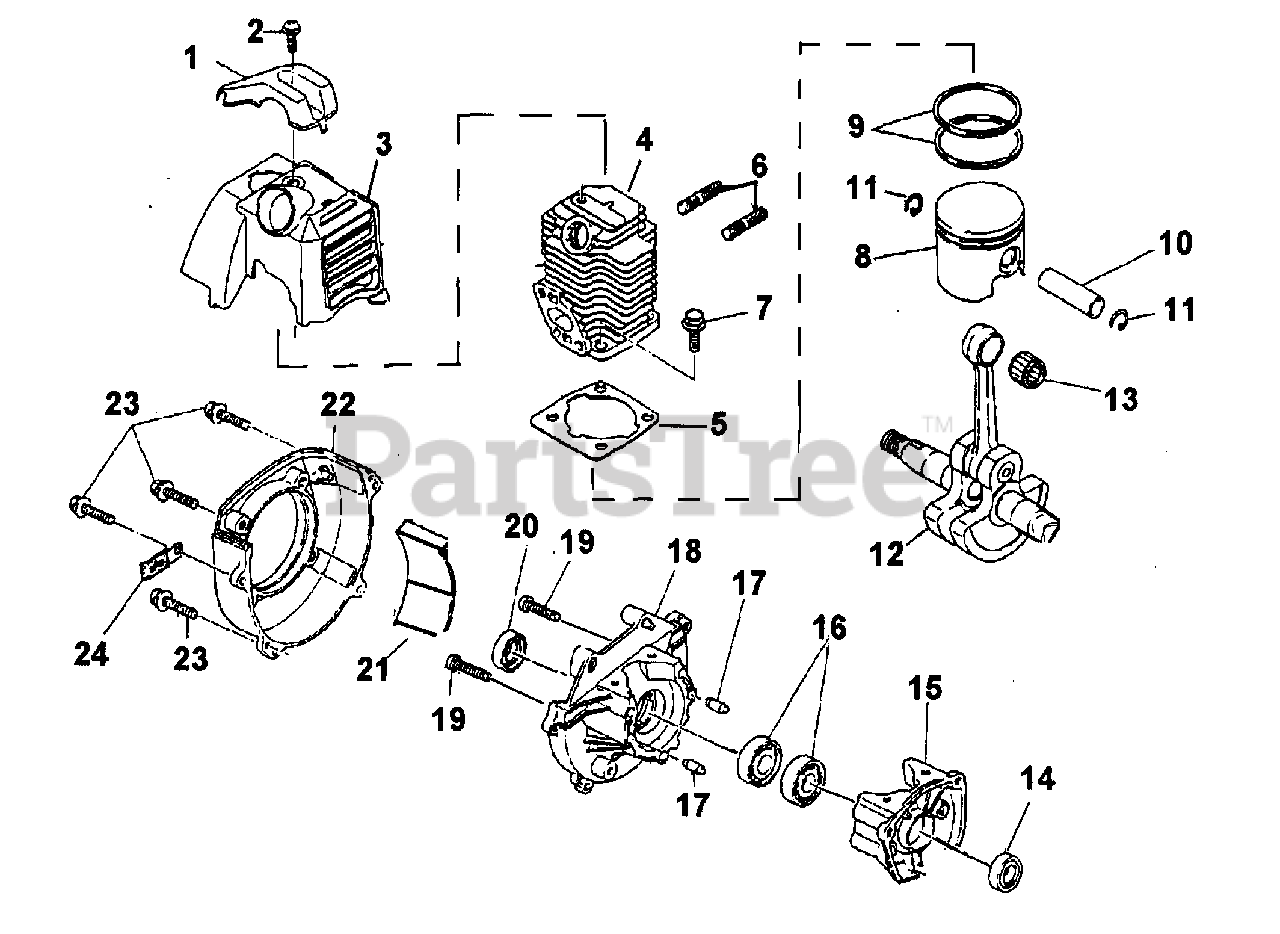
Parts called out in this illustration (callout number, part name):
1	GUARD, PLUG
2	SCREW & WASHER
3	COVER, TOP
4	CYLINDER ASSY.
5	GASKET, CYLINDER
6	BOLT, STUD
7	BOLT & WASHER
8	PISTON ASSY
9	RING, TOP
10	PIN, PISTON
11	CLIP, PISTON PIN
12	CRANKSHAFT ASSY.
13	BEARING, NEEDLE
14	OIL SEAL
15	CASE, STARTER
16	BEARING, BALL
17	PIN, DOWEL
18	CASE, DRIVE
19	SCREW, PAN HEAD
20	OIL SEAL
22	CASE, FAN
23	BOLT & WASHER
